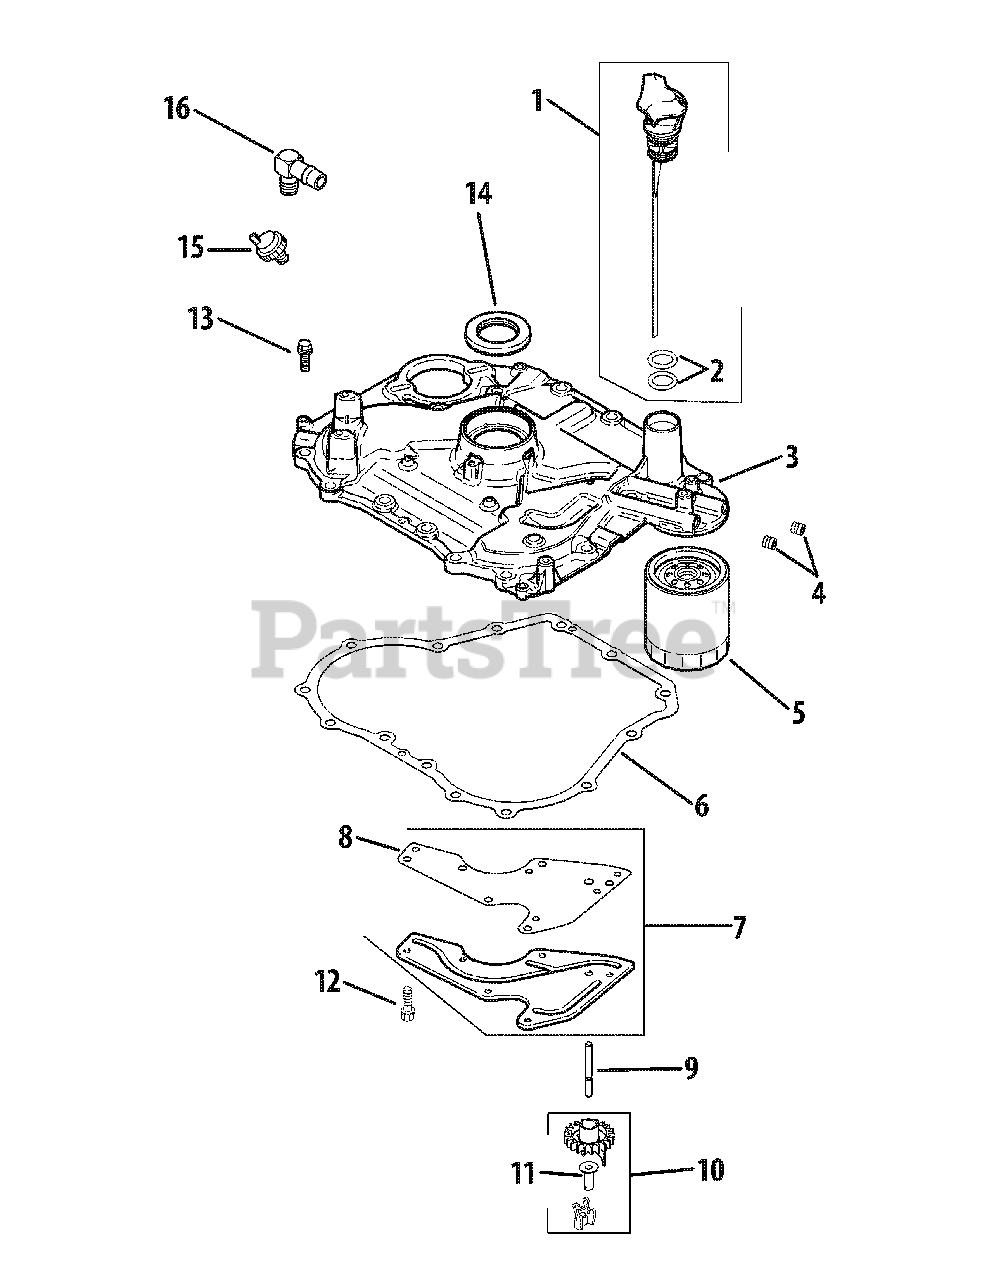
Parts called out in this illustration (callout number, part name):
1	Dipstick w/ 2 O-Rings (Inc. 2)
2	O-Ring
3	Closure Plate Assembly Kit
4	CTSK Pipe Plug, 1.8"
6	Closure Plate Gasket
7	Oil Passage Cover Kit (Inc. 8)
8	Oil Passage Gasket
9	Governor Cross Shaft
10	Governor Gear Kit (Inc. 11)
11	Governor Regulating Pin
12	Flg Thd Frm Screw, M5 x 0.8 x 13
13	Hex Flange Screw, 1.2 Dog Point
14	Oil Seal
15	Oil Pressure Switch
16	90 Connector Hose
